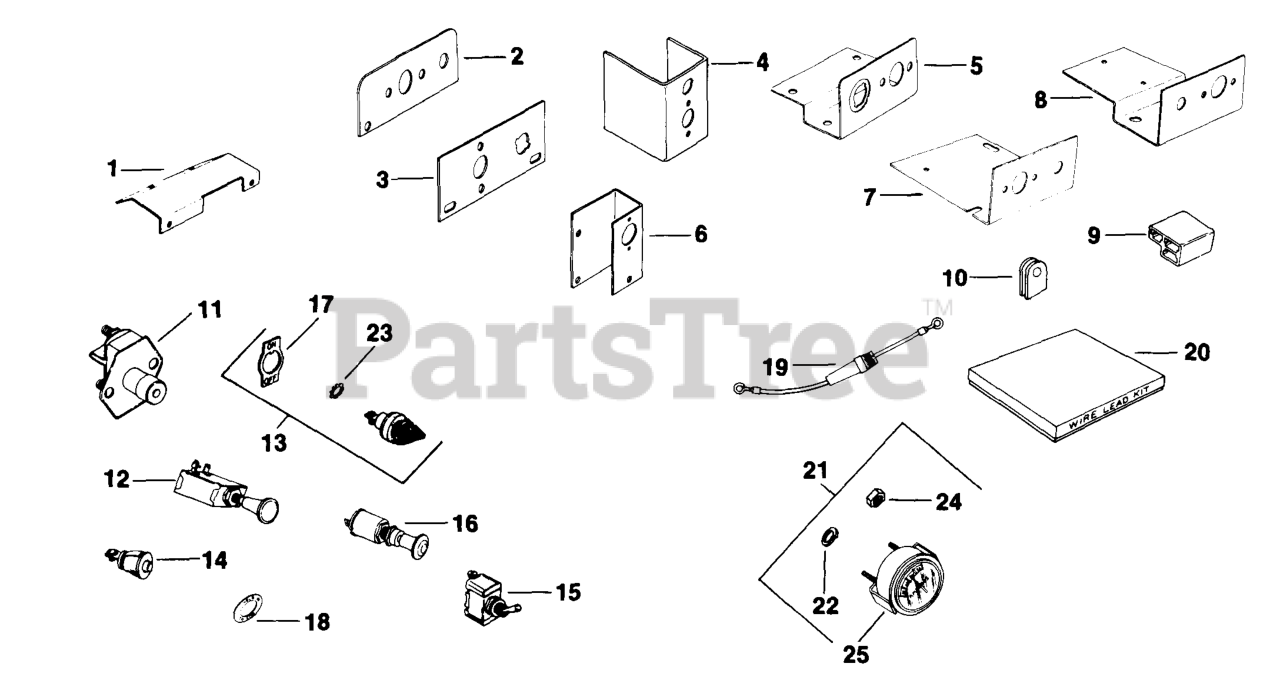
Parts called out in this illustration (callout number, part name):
11	SWITCH - DISCONTINUED
13	KIT, IGNITION SWITCH - DISCONTINUED
17	PLATE - DISCONTINUED
18	PLATE - DISCONTINUED
23	WASHER, EXT TOOTH LOCK 1/2"-DISC.
